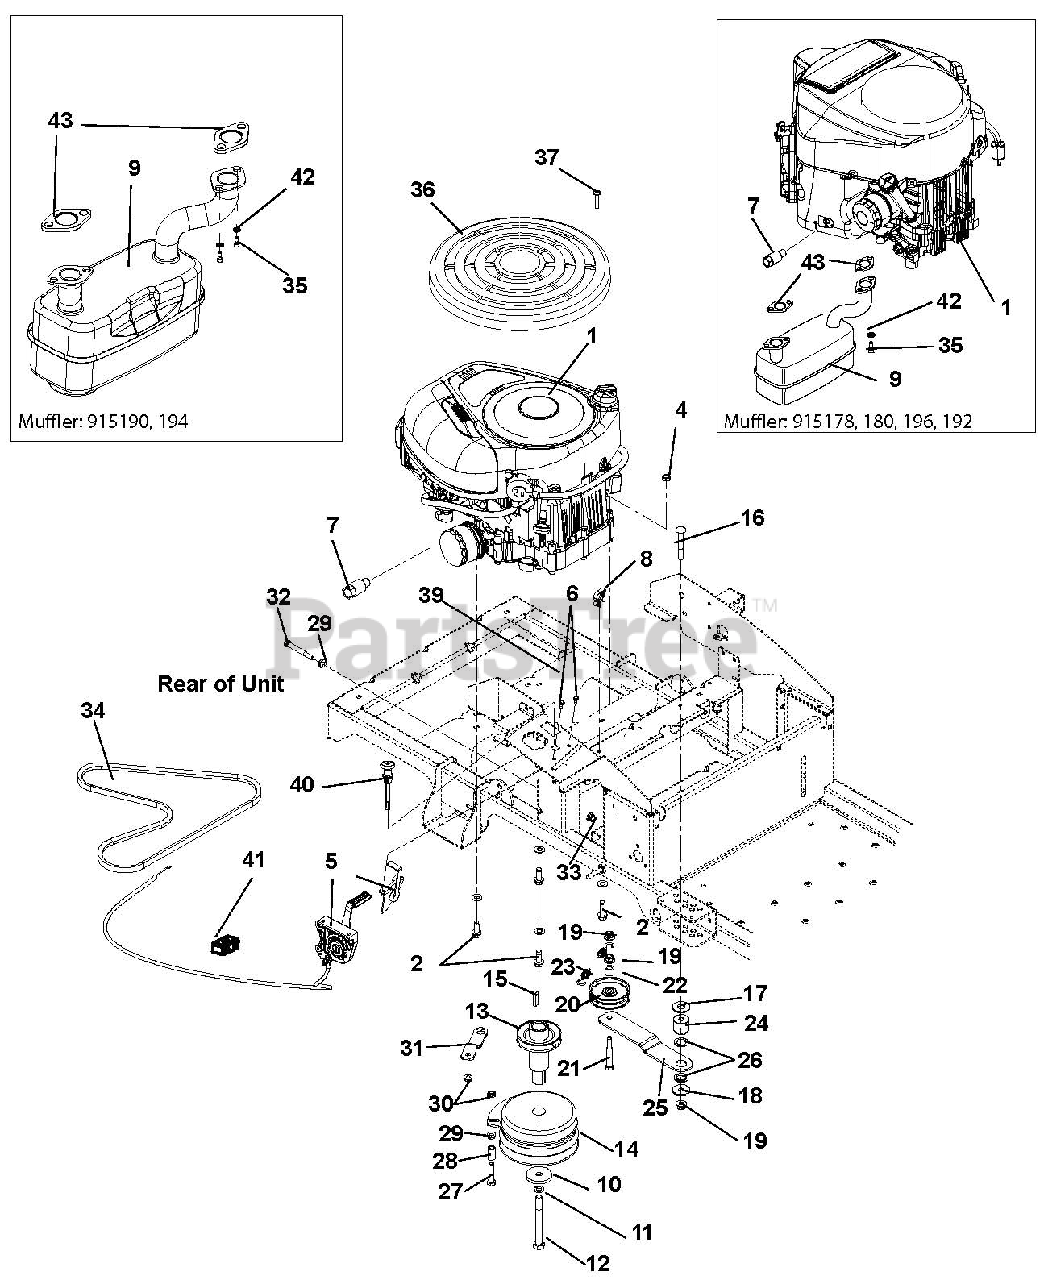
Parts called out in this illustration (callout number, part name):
1	Engine, Kohler 25 HP Pro
1	Engine, Koher 24 HP Pro
1	Engine, BS 18 HP TWN
1	Engine, Kohler TWN - 22 HP
2	Screw, Tapping .38-16 x 1.25 Hex Washer Head
3	Bolt, Hex .38-16 x 1.25
4	Nut, Locking Jam .375-16
5	Cable, Throttle
5	Cable, Throttle/Choke
6	Screw, Tapping 10-24 x .50 Hex Washer Head
7	Oil Drain
8	Wire Clip, for 25" hole
9	Muffler, Kohler Twin
9	Muffler, Twin Briggs and Stratton
10	Washer, Flat Steel .469 x 2.00 x .25
11	Washer, Locking .44 x .109 Regular
12	Bolt, Hex .44-20 x 4.50 Grade 8
13	Weldment, Crankshaft Extension
14	Clutch, 105 FT*LB MONO Pole
15	Key, Square .25 x 1.25 x .25 SAE 8630 or SAE 1035
16	Bolt, Round Head Square Neck .38-16 x 2.75
17	Washer, Flat Steel .563 x 1.38 x .109
18	Washer, Flat Steel .406 x 1.375 x .135
19	Nut, Locking Nylon Flange .38-16
20	Pulley, Engine Clutch
21	Bolt, Hex .38-16 x 2.75
22	Bushing, Sleeve .391 x .688 x .52
23	Spring, Extension
24	Spacer, Ground Drive Idler
25	Idler Arm, Ground Drive
26	Bushing, Idler Arm
27	Screw, Cap .31-18 x 1.75
28	Spacer, Rubber 5/16 ID x 1.0
29	Nut, Spin Lock Flange .312-18
30	Nut, Locking Top Flange .31-18
31	Bracket, Clutch Stop
32	Bolt, Hex .31-18 x 2.75
33	Nut, Locking Nylon Flange .31-18
34	V-Belt, HA-RAW Edge Laminated
35	Cap screw 31-18 x .75 S/HD
36	Guard, Briggs Engine
37	Screw, 8-16 x .87
38	Screw, Tapping .25-20 x .50 Hex Washer Head
39	Plug 5/8" SQ Black
40	Cable, Choke
41	Cable Clip
42	Washer, Locking .31 x .078 Regular
43	Gasket, Muffler Courage TWN
